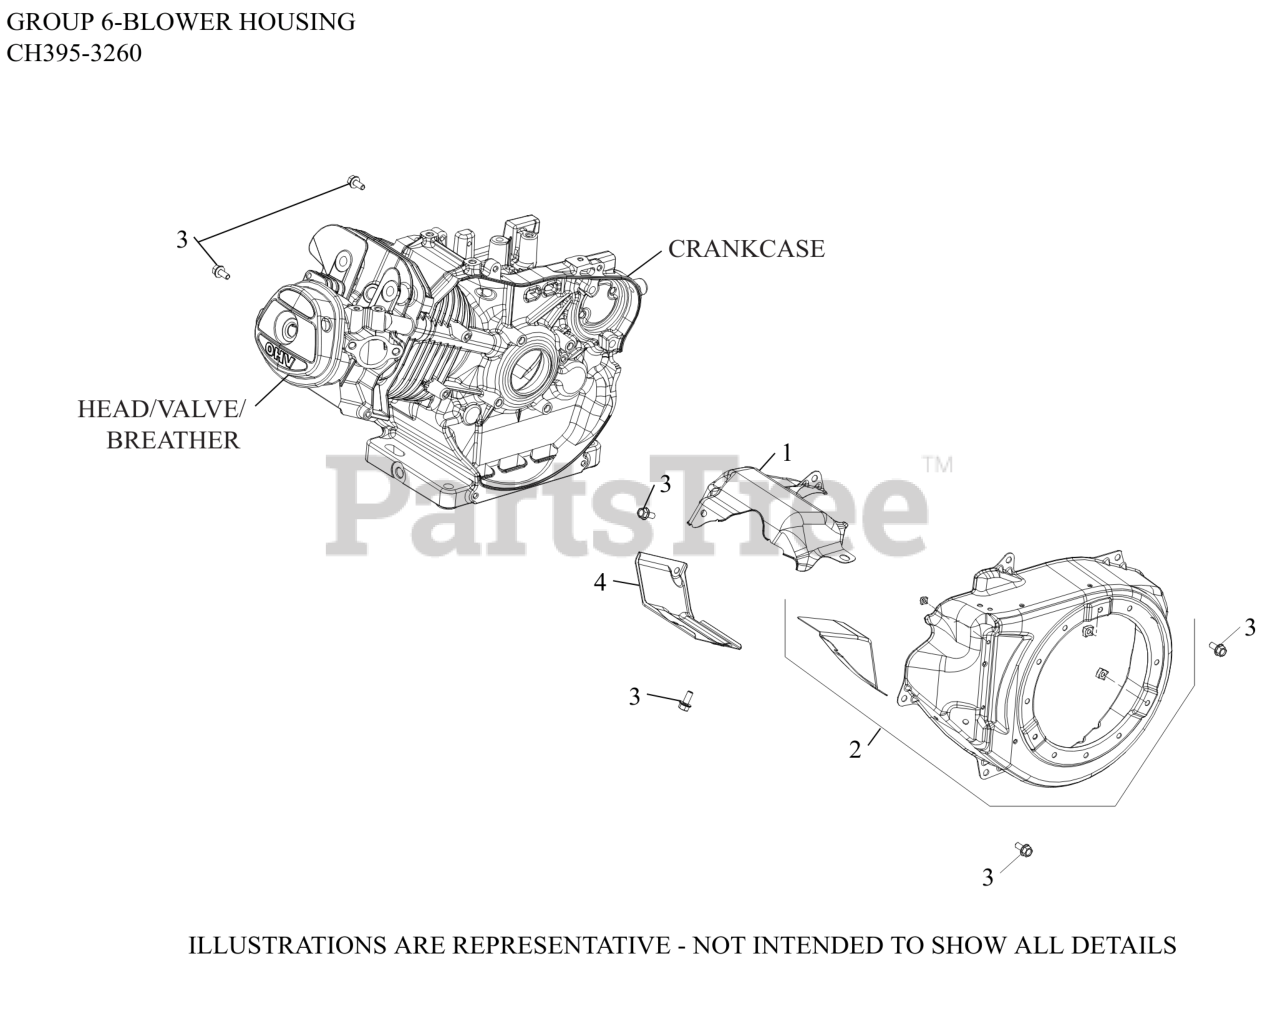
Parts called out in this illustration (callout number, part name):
1	SHIELD, UPPER HEAT
2	HOUSING, BLOWER ASSEMBLY
3	SCREW, HEX FLANGE (M6)-USE 25 086 433-S
4	SHIELD, CYLINDER HEAD
